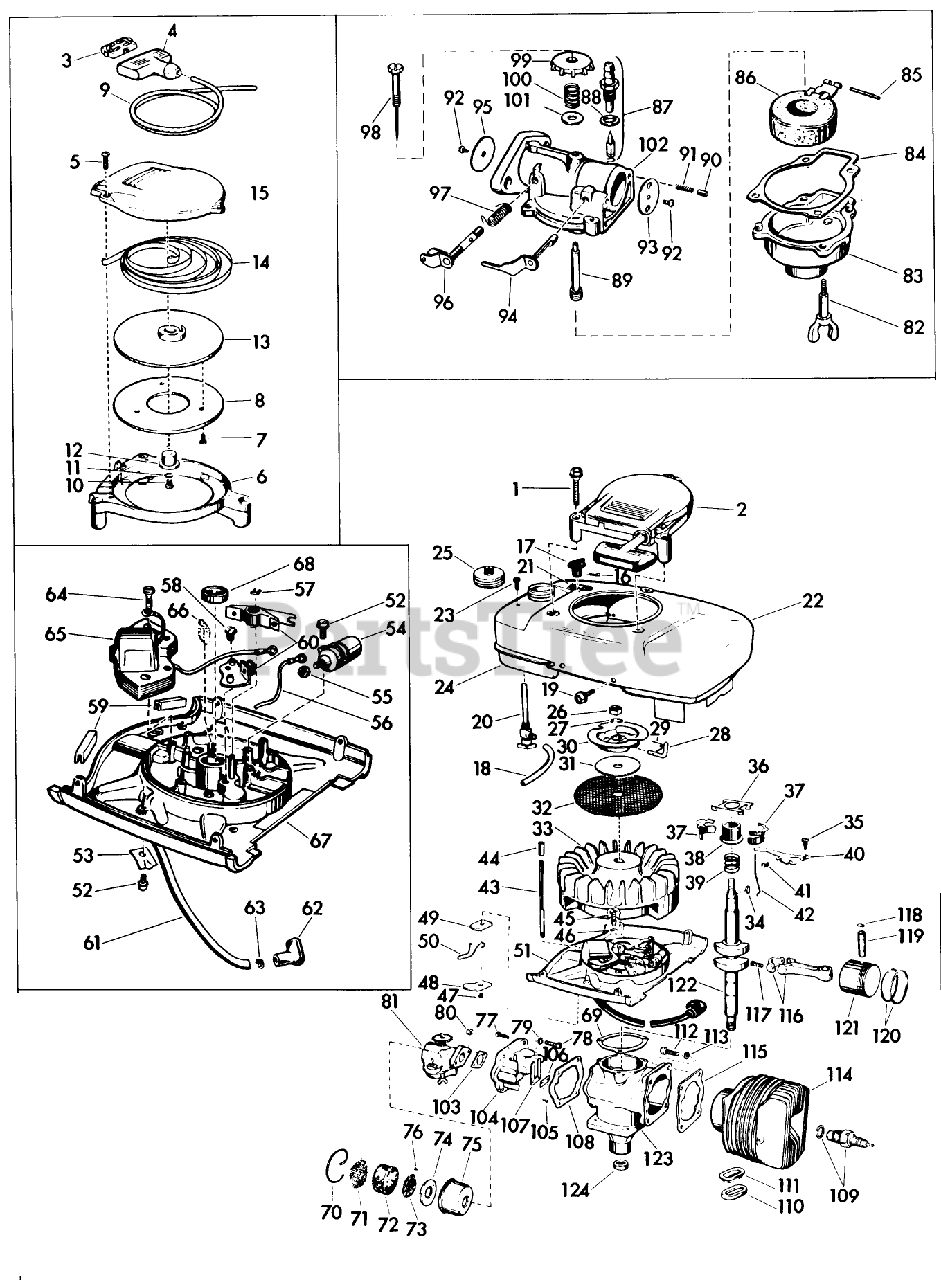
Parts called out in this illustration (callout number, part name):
6	Base-Starter
10	Screw-Pulley to Cap
11	Washer-Lock, Pulley
14	Spring-Recoil
16	Cotter Pin-Choke Knob
17	KNOB, CHOKE BAR
19	SCREW S
20	VALVE&SCREEN SM
28	PIN - STARTER
38	COLLAR S
40	GOVERNER LEVER AY
41	WEAR BLOCK S
42	GOVERNOR ROD S
45	Screw-Pulley to Cap
46	Washer-Lock, Pulley
47	Screw Shut-off Switch
57	Spring Clip-Breaker Post
60	BREAKER AY. S
62	Cover-Rubber
66	Oiler Wick
69	GASKET S
72	ELEMENT
74	BACK-UP PLATE
77	SCREW S
80	STOP NUT
92	Screw-Choke Disc
94	CHOKE SHAFT&LVR AY
97	SPRING
98	NEEDLE AY. S
100	Spring-Ndl. Adj.
101	Washer-Needle Adjustment
103	GASKET S
106	PLATE-BACKUP, REED
109	Spark Plug
113	Washer-Lock, Cylinder to Crankcase
114	Cylinder Sleeve Assembly
117	Screw-Connecting Rod
120	Ring-Piston
122	Crankshaft
